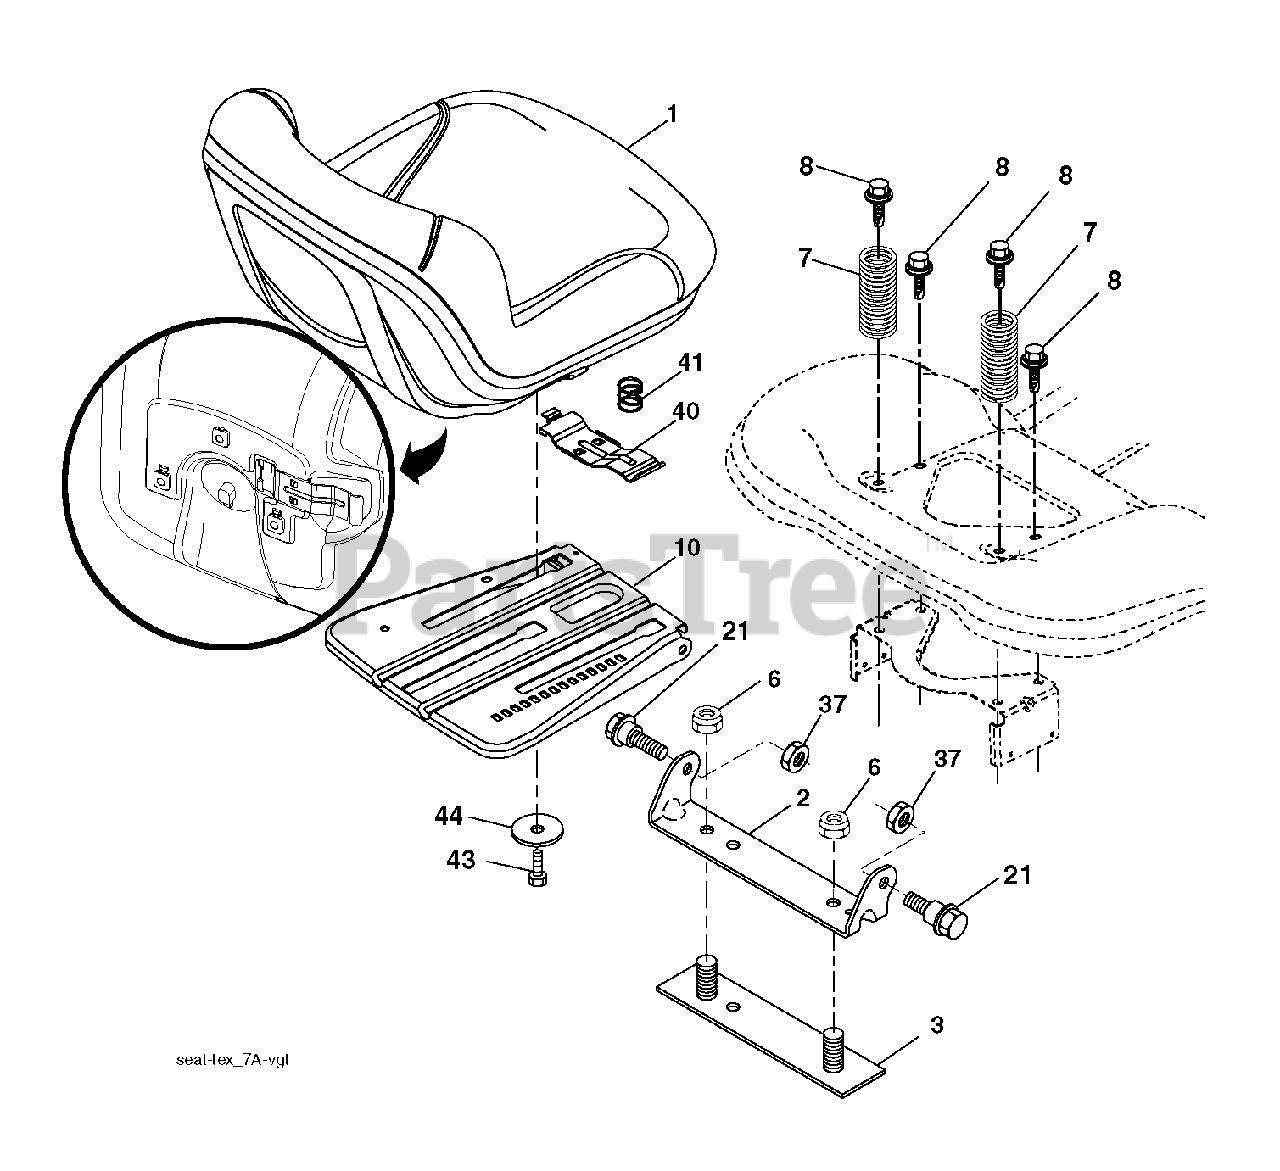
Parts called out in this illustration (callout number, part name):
1	SEAT.TH130.GREY.HUSQ.TEX
2	BRKT.PIVOT.FENDER
3	STRAP
6	NUT
7	SPRING COMPRESSION
8	BOLT, 5/16-18 X 1 3/4
10	PAN.ASM.SEAT.3PT
21	BOLT.SHOULDER.5/16-18
37	NUT.71038.31-18.HEX.NYLOCK
40	HANDLE.SLIDE.SEAT.TEX.BLACK
41	SPRING.LATCH.SEAT.TEX
44	WASHER 13/32 X 2-3/8 X 12GA
